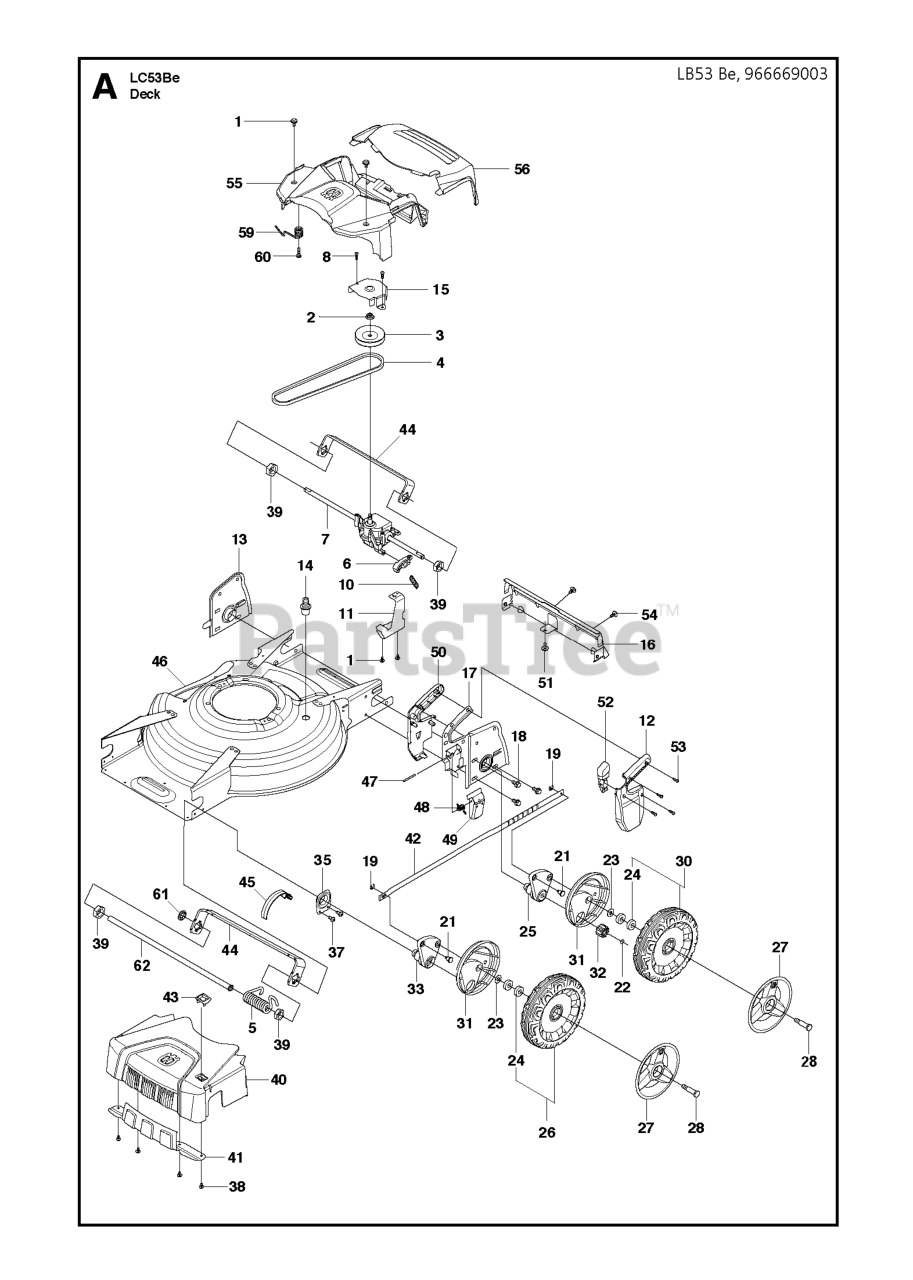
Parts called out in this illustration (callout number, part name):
1	SCREW ITXPANTT M5X10 ZPB (A00
4	BELT WRAPPED V-BELT Z 31 3/4"
8	SCREW ITXPANT T50X16 ZN/FE (A
19	FASTENER
24	BALL BEARING
37	SCREW ITXPANTT M5X10 ZPB (A00
38	SCREW ITXPANTT M5X10 ZPB (A00
51	SCREW ITXPANTT M5X10 ZPB (A00
53	SCREW ITXPANT T50X16 ZN/FE (A
54	SCREW ITXPANTT M5X10 ZPB (A00
57	SCREW ITXPANTT M5X10 ZPB (A00
60	SCREW ITXPANT T50X16 ZN/FE (A
